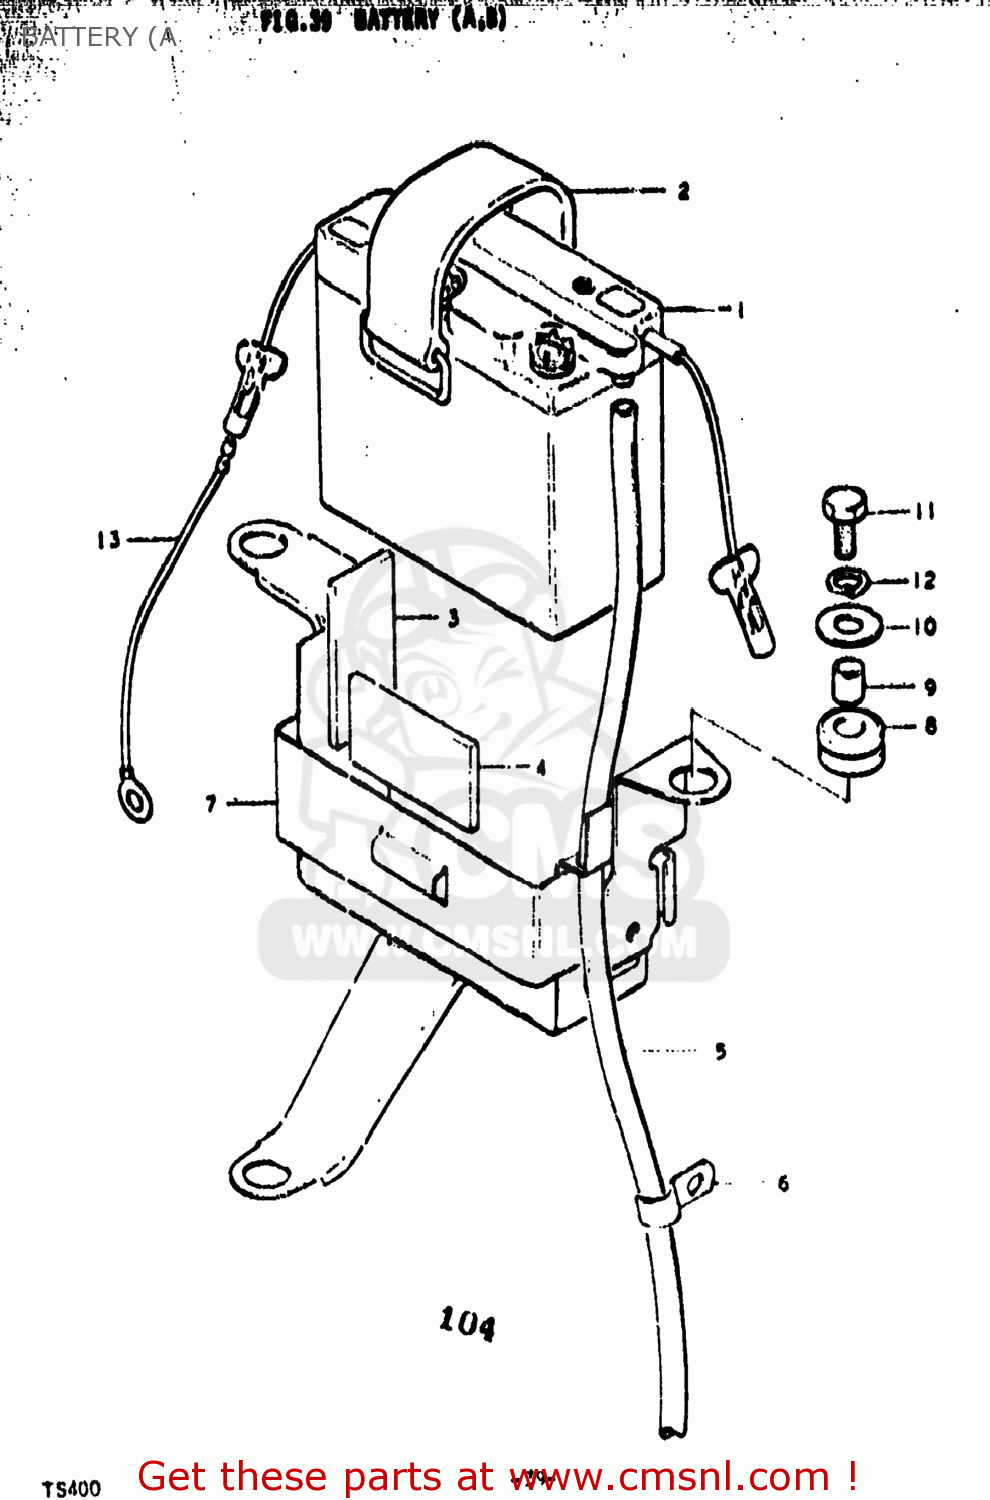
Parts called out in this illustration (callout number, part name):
1	BATTERY ASSEMBLY
2	BAND
3	CUSHION,BATTERY
4	CUSHION(30X50X3)
5	HOSE,BATTERY EXHAUST
6	CLAMP
7	HOLDER,BATTERY
8	CUSHION
9	SPACER (7X9X7)
10	WASHER (6.5X20X1.2)
11	BOLT
12	LOCK WASHER
13	LEAD WIRE
14	WIRE,BATTERY LEAD
